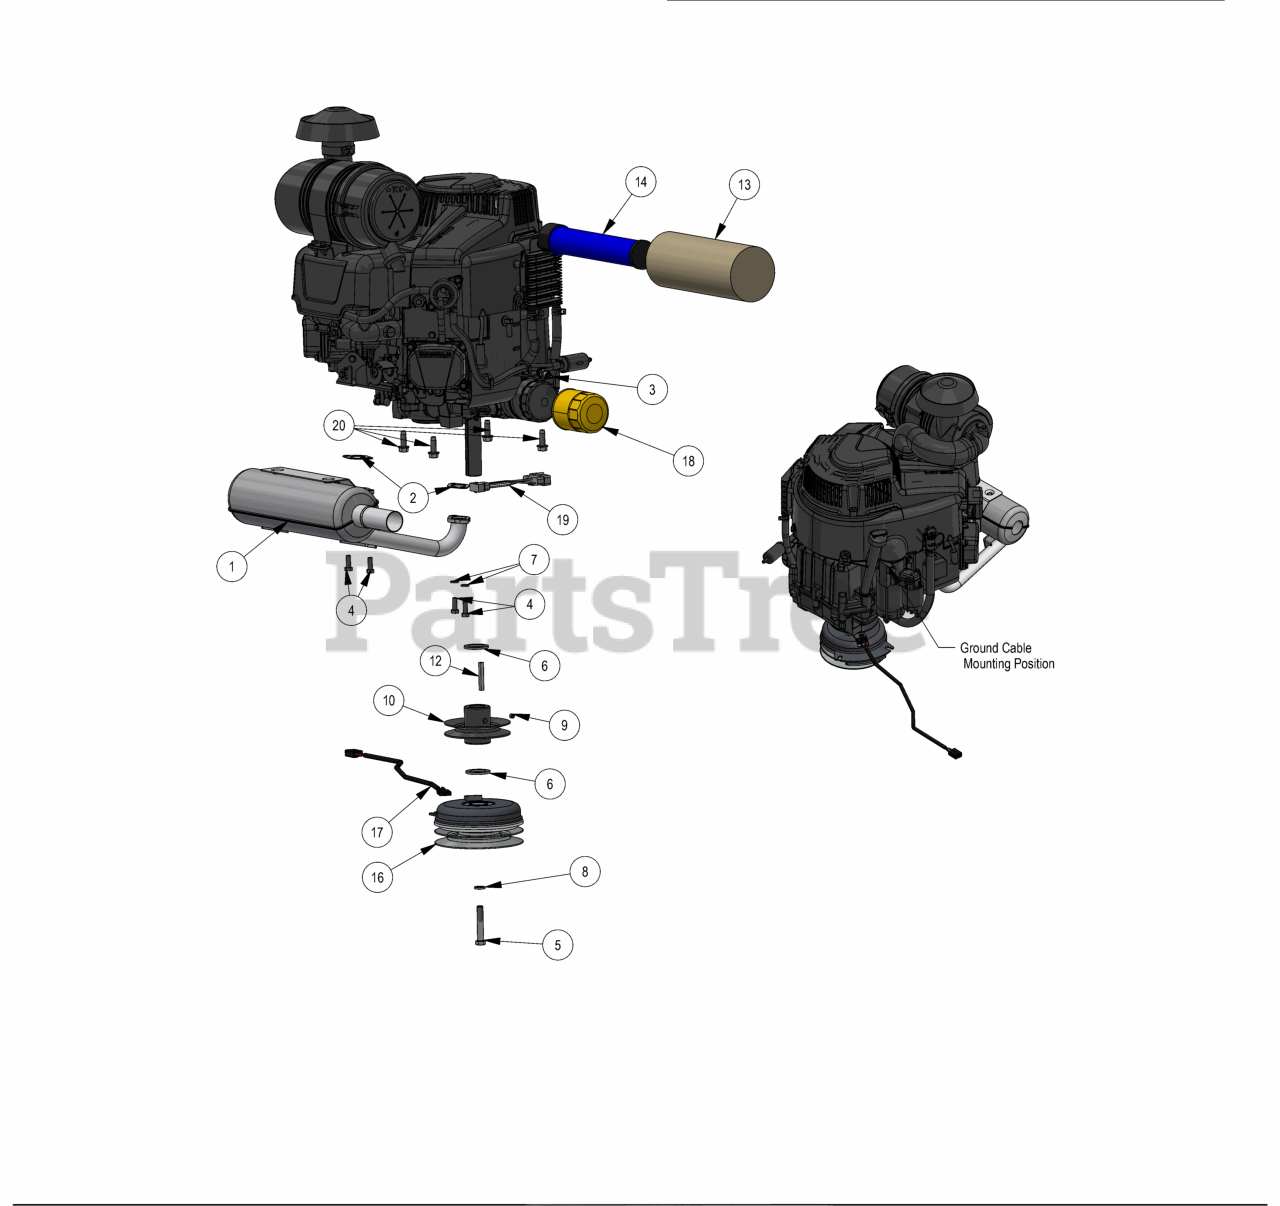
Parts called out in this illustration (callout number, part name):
1	Briggs 28 EFI Exhaust Revolt
2	Exhaust Gasket
3	Spark Plug
4	Torx Bolt-Exhaust
5	7/16-20 X 2-1/2 HEX CAP SCREW (GR.8) ZINC YELLOW
6	1.140 ID X 1.750 OD X .132 THICK FLAT WASHER PLAIN
7	5/16 SPLIT LOCKWASHER ZINC
8	7/16 SPLIT LOCKWASHER (GR.8) ZINC YELLOW
9	5/16-24 X 1/4 SOCKET SET SCREW (CUP PT) PLAIN
10	4 3/4 Motor Pulley
11	5 3/4 Idler Pulley-Don Dye (61" Deck Only)
12	1/4 X 2 SQ MACHINERY KEY 1018 STL PLAIN
13	Canister Air Filter- Outer
14	Canister Air Filter- Inner
16	Clutch Assembly
17	Clutch Pigtail
18	Oil Filter
19	2021 28 Briggs EFI Pigtail
20	3/8-16 X 1-1/8 HEX WASHER UNSLOT SERRATED (TRI-LOB) TRS ZINC YELLOW
